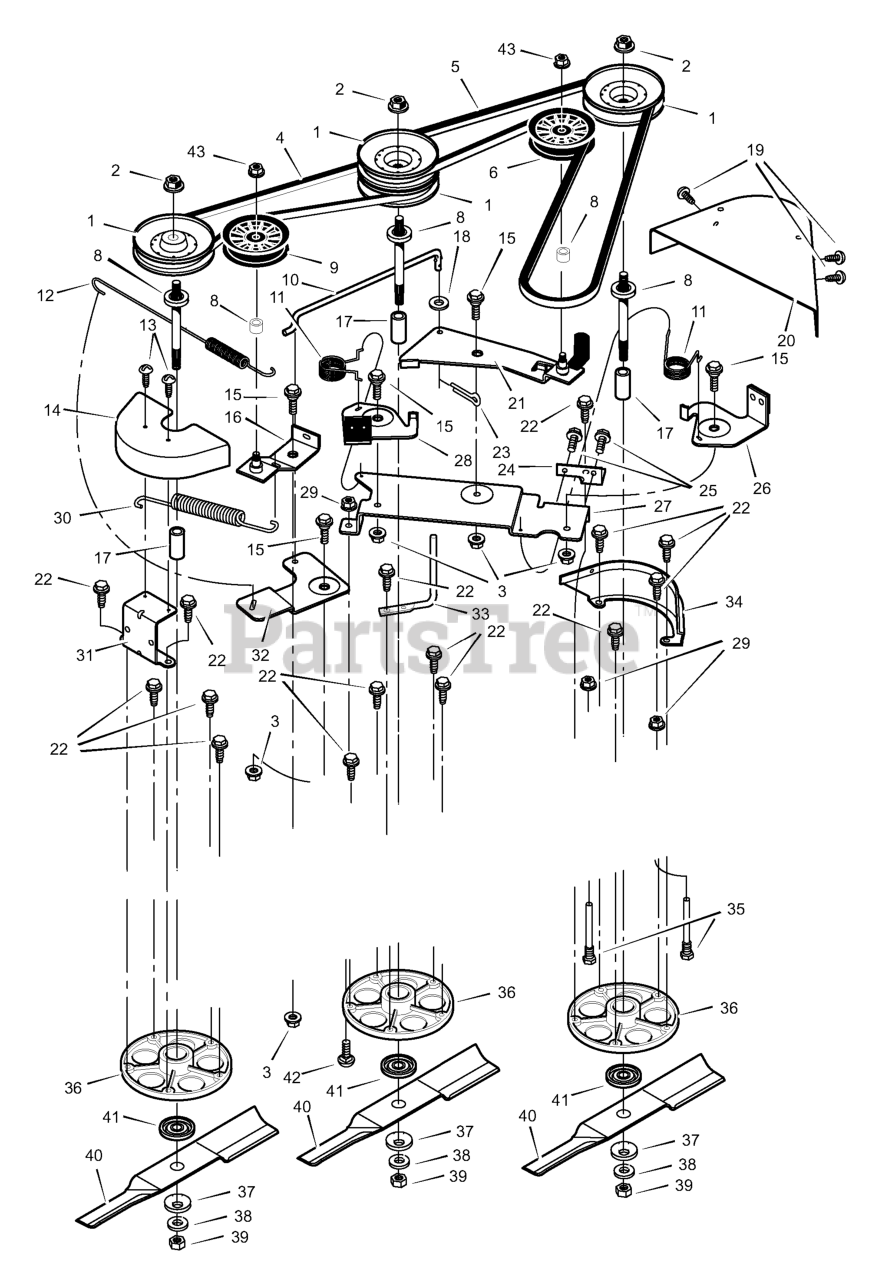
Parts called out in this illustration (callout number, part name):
1	Pulley
3	Nut
4	Belt, Secondary
5	Belt, Primary
6	Pulley, Idler
8	Jackshaft
9	Pulley, Idler
10	Link, Bell Crank
13	Screw
14	Cover, Right Pulley
15	Bolt, Shoulder
16	Arm Assembly, Idler
18	Washer
20	Cover, Left Pulley
21	Arm Assembly, Idler
22	Bolt
23	Pin, Cotter
24	Bracket, Brake Plate
26	Brake Assembly, Left
27	Plate, Brake Arm
28	Brake Assembly, Center
29	Nut, Flange
31	Bracket, Cover
32	Bell Crank
33	Guide, Belt
34	Bracket, Pulley Cover
35	Guide, Belt
36	Housing, Jackshaft
39	Nut, Blade
41	Adapter, Blade
42	Bolt, Carriage
43	Nut
